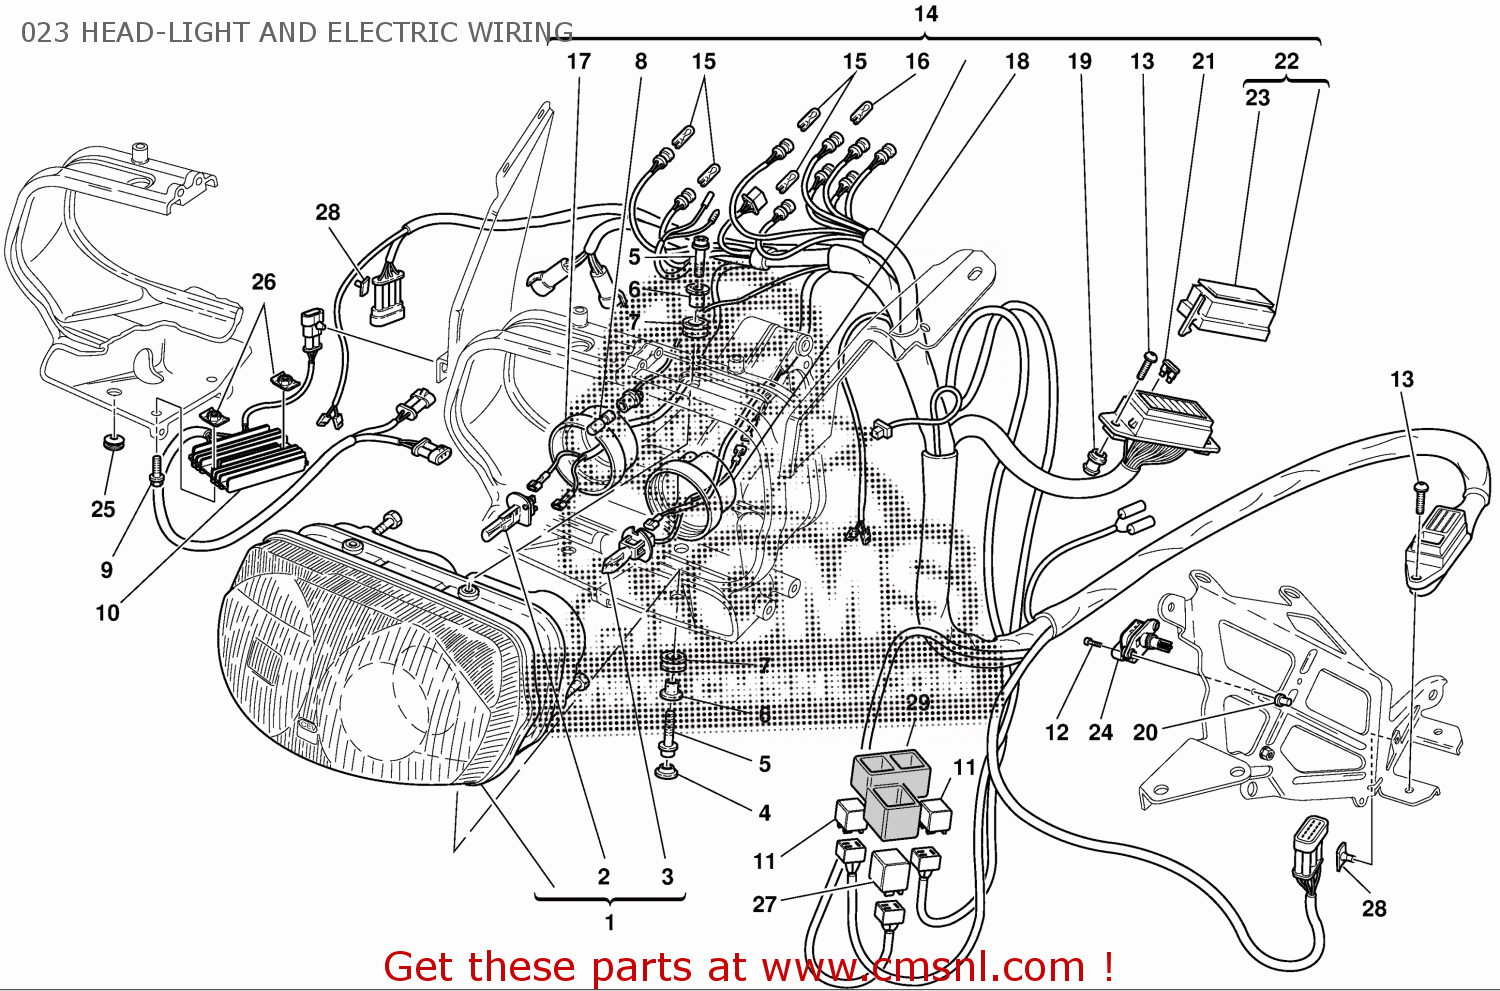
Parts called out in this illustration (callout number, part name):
1	HEADLIGHT
2	BULB 12V 55W H1 HALOGEN
3	BULB 12V 55W H3 HALOGEN
4	FAIRLEAD
5	SCREW M6X20
6	SPACER
7	RUBBER PAD
8	WEDGE BASE BULB 12V5W
9	SCREW M6X30
10	VOLTAGE REGULATOR
11	RELAY SIEMENS A-303/B1008
12	SCREW M4X20
13	SCREW TSEI M5X0.8X10
14	WIRING
15	WARNING LAMP BULB 12V-3W
16	BULB 12V 1.2W T5
17	HEADLIGHT COVER
18	HEADLIGHT COVER
19	PIN
20	THREADED INSERT
21	FUSE 3A
22	CASE COVER
23	STICKER SCHEMA FUSIBILI
24	SENSOR, PRESSURE
25	VIBRATION DAMPER PAD
26	PLATE
27	FLASHER RELAY
28	QUICK FASTENING
29	MOUNT RUBBER
